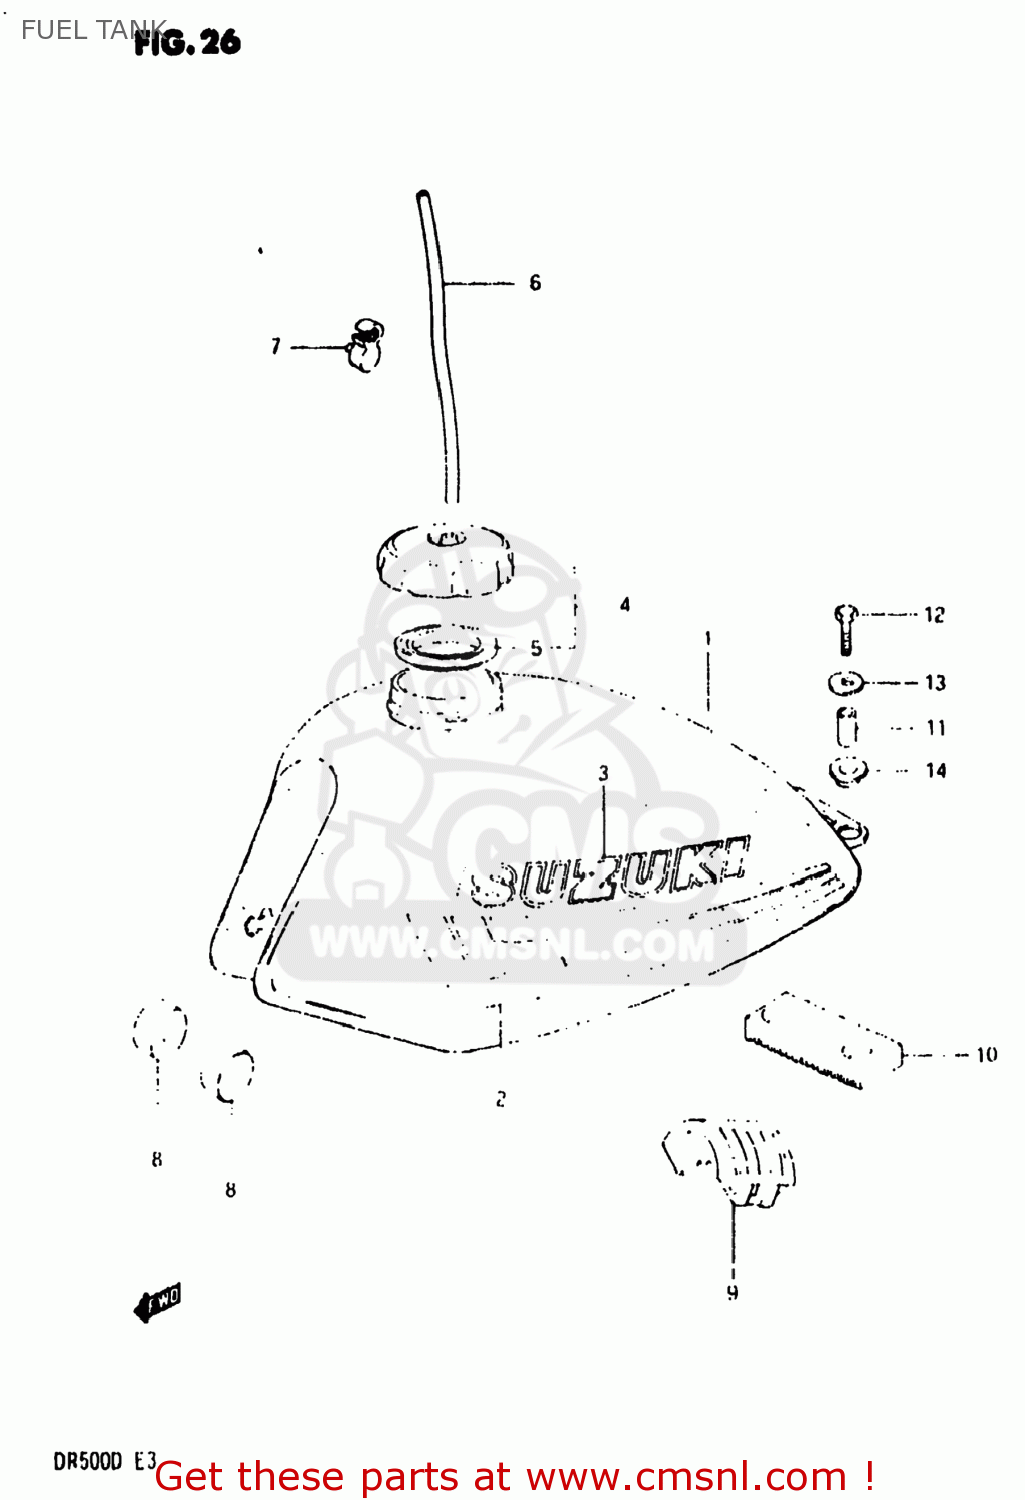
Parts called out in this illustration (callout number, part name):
1	TANK ASSEMBLY,FUEL
2	TAPE SET,FUEL TANK
3	EMBLEM
4	CAP,FUEL TANK
5	GASKET,FUEL TANK CAP (NAS)
6	HOSE
7	CLAMP,FUEL TANK BREATHER HOSE
8	CUSHION
9	CUSHION,FUEL TANK UPR FR
10	CUSHION,FUEL TANK,REAR
11	SPACER (6.5X10.5X29)
12	BOLT 6X40
13	WASHER (6.5X24X1.6)
14	CUSHION
